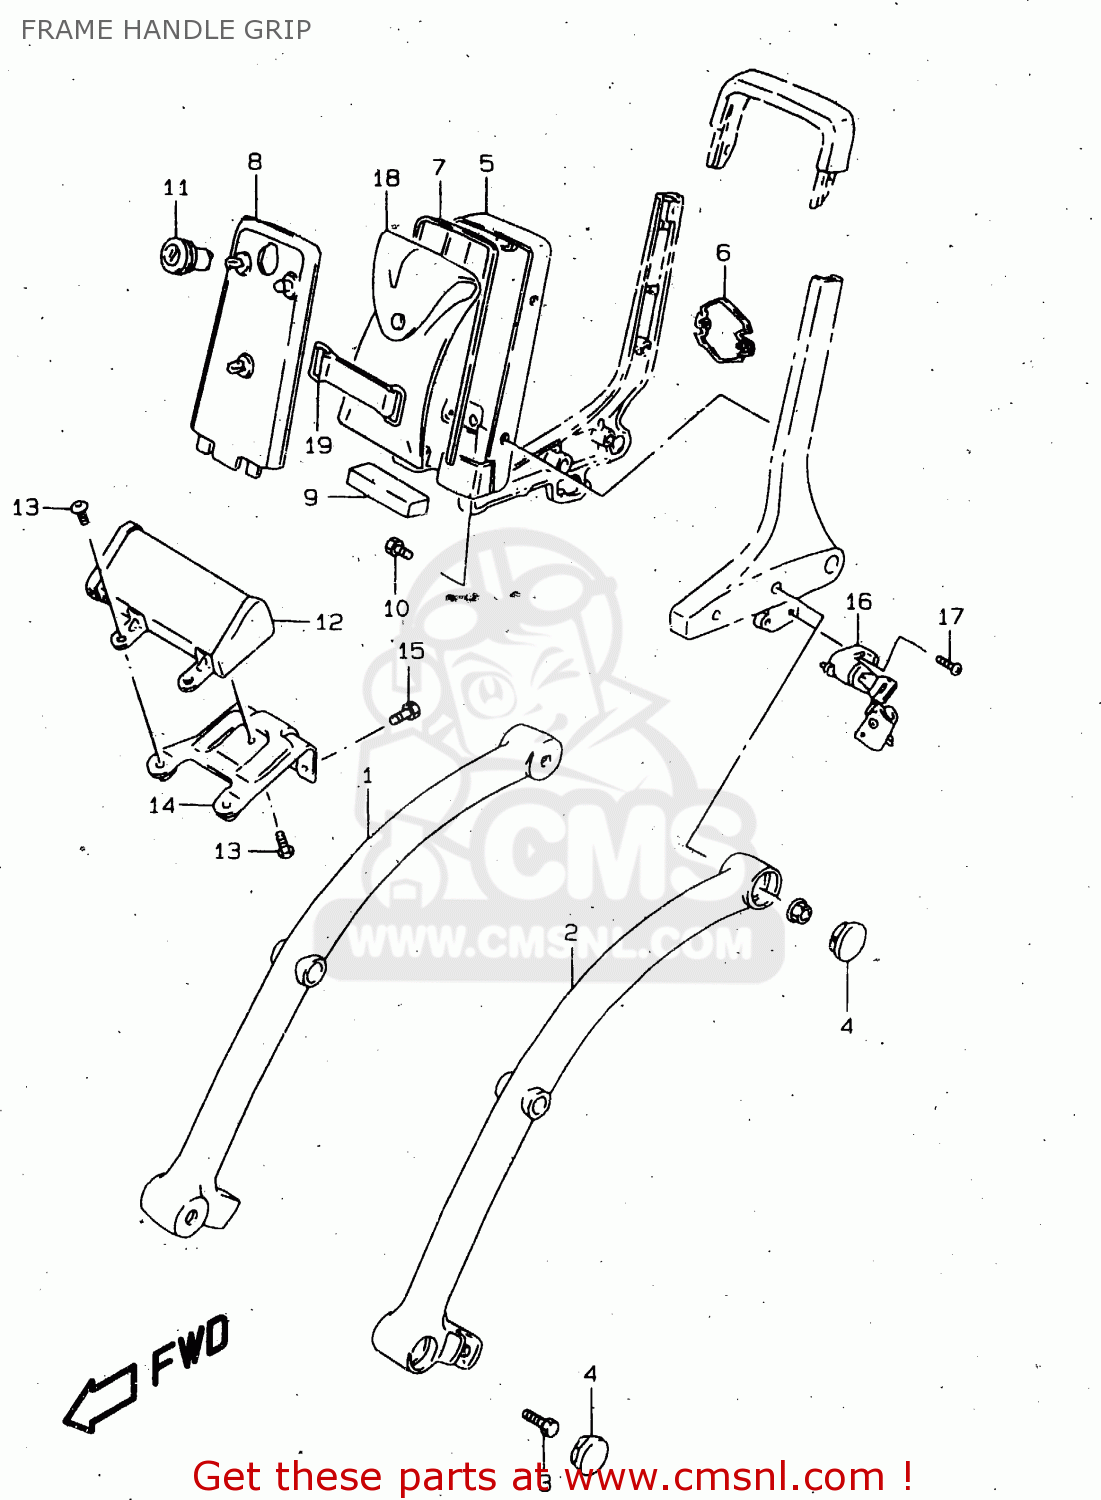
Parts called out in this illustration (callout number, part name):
1	GRIP,FRAME HANDLE,R
2	GRIP,FRAME HANDLE,L
3	BOLT
4	CAP(OD:11)
5	HOLDER,TOOL RR
6	EMBLEM,TOOL HOLDER RR
7	MOLDING,TOOL HOLDER RR
8	HOLDER,TOOL FR
9	CUSHION,TOOL BACK
10	BOLT
11	LOCK SET,TOOL HOLDER
12	HOLDER ASSY,TOOL
13	SCREW(6X12)
14	BRACKET,TOOL HOLDER
15	BOLT
16	LOCK SET,HELMET
17	SCREW
18	TOOL ASSY
19	BAND
